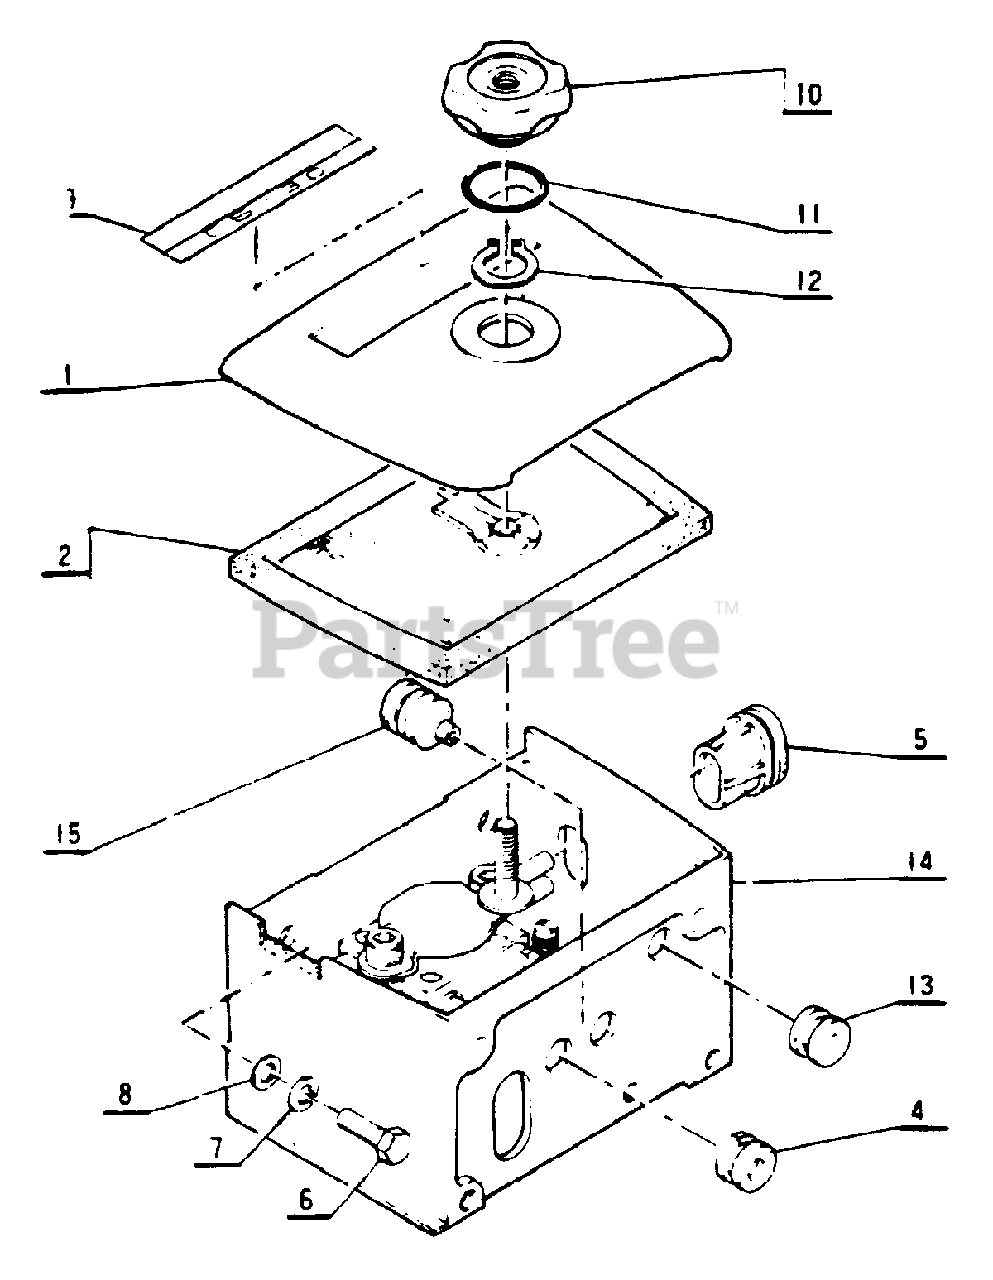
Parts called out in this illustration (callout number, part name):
1	COVER, AIR FILTER
2	FILTER, AIR
5	GROMMET
6	BOLT - 5X12
7	LOCKWASHER - 5
8	WASHER - 5
9	LABEL - MODEL
10	WINGNUT
11	O-RING
12	RING, RETAINING - 11
14	CASE, CARBURETOR
